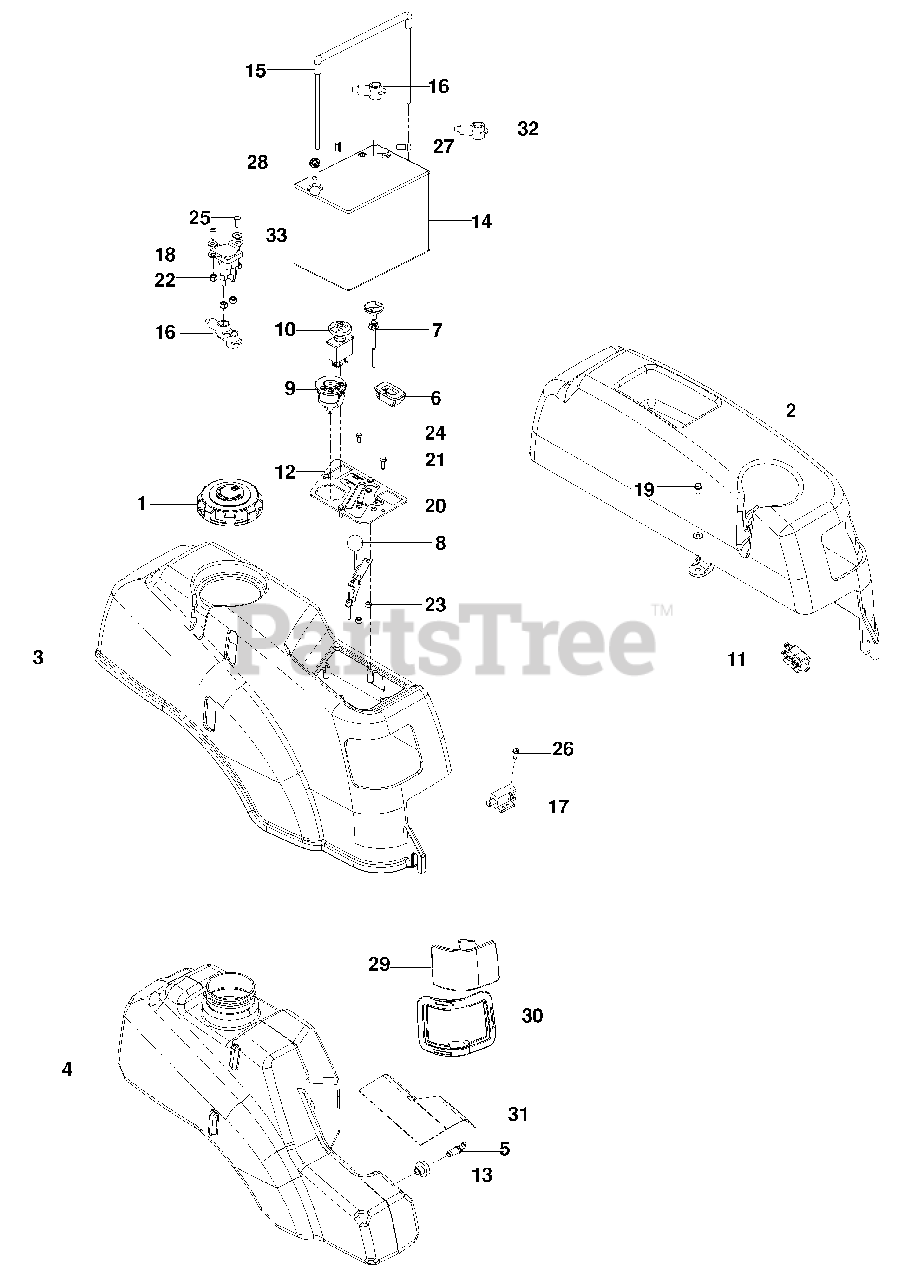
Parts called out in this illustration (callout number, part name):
2	Fender, Lt
3	Fender, Rt
4	Tank, Fuel
5	Elbow, Tank
6	Hour Meter
7	Control, Choke
8	Cable, Throttle
9	Switch, Ignition
10	Switch, Clutch
11	Switch, Brake
12	Plate, Control
13	Grommet, Rubber
14	Battery
15	Tie Down, Battery
16	Terminal Cover
17	Switch, Nc
19	Bolt 1/4-20 X 1/2 Hwst
20	Decal, Console
21	Screw 10-24 X 1/2 Slt Hd
22	Nut 1/4-20 Hex Nyloc
23	Nut 10-24 Hex Nyloc
24	Screw 10-12 X 3/4 Wsh Hd
25	Screw 1/4-20 X 5/8 Btn Skt
26	Screw 10-24 X 5/8 Wsh Hd
27	Rhsnb 5/16-18 X 3/4
28	Nut 5/16-18 Flange Nyloc
29	Lens, Lt
30	Lens Rim, Lt
31	Shield, Heat
33	Washer 1/4 Int Tooth Lk
